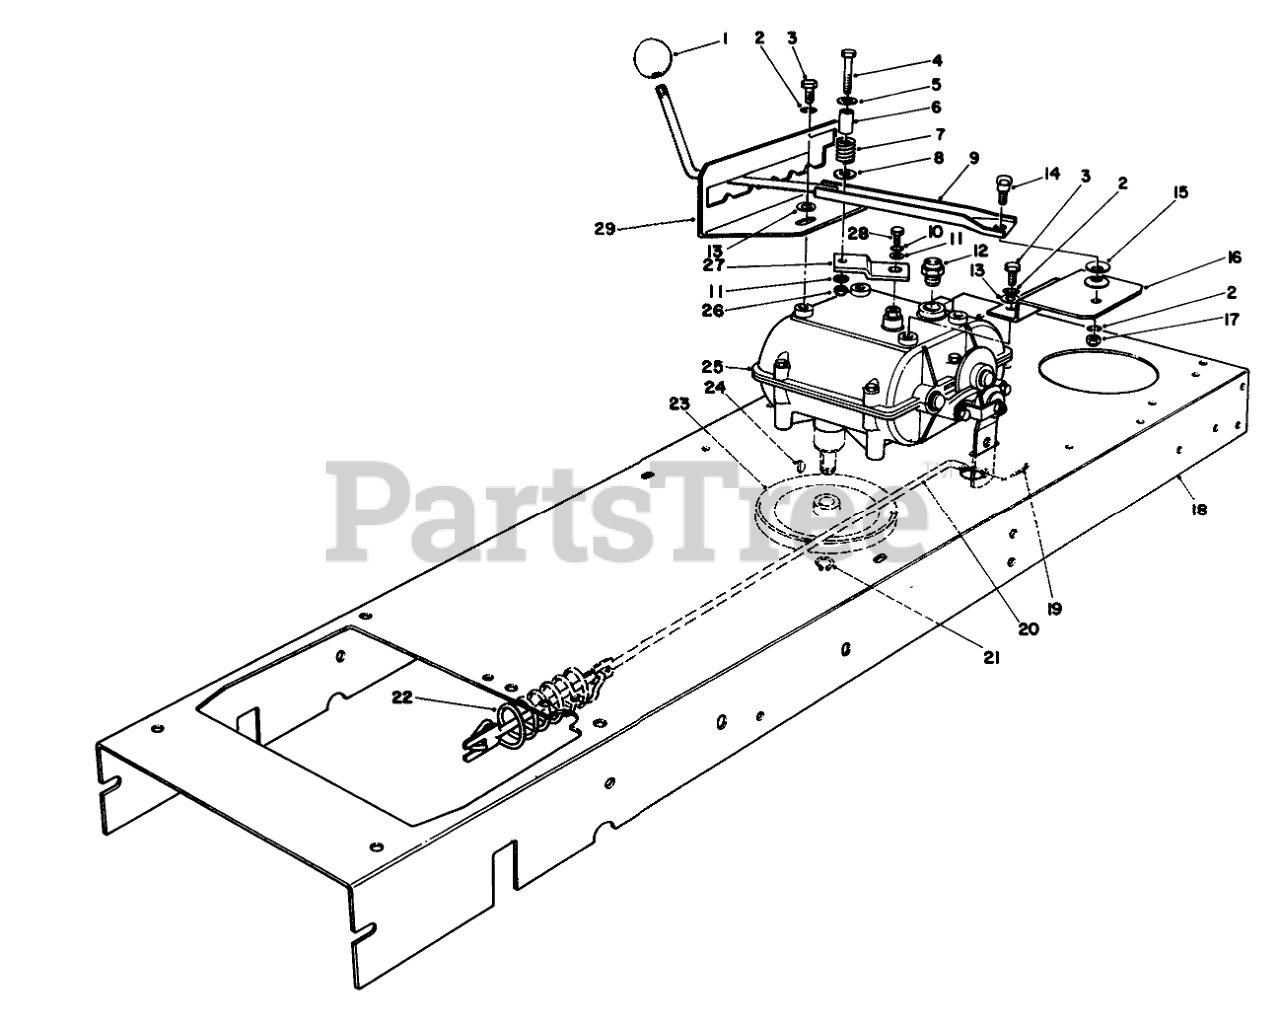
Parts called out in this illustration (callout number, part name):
2	Lockwasher
3	SCREW-HWHTF
4	SCREW-HH
5	WASHER-FLAT
6	SPACER-SPLIT
7	SPRING-COMPRESSION
8	WASHER-FLAT
9	SHIFT LEVER WA B
10	WASHER-LOCK
11	WASHER-FLAT
12	NEUTRAL SWITCH
13	WASHER-PLAIN
14	SCREW-SHOULDER
15	WASHER-BELLEVILLE
16	SHIFT MTG BRKT
17	NUT-LOCK, NI
18	Frame-Main
19	PIN-COTTER
20	BRAKE ROD
21	RING-SNAP, EXTERNAL
22	SPRING-EXT
23	PULLEY
24	KEY-WOODRUFF
25	TRANSMISSION
26	NUT-LOCK, CONE
27	LEVER-SHIFT
28	SCREW-HH
29	Gate-Shift
